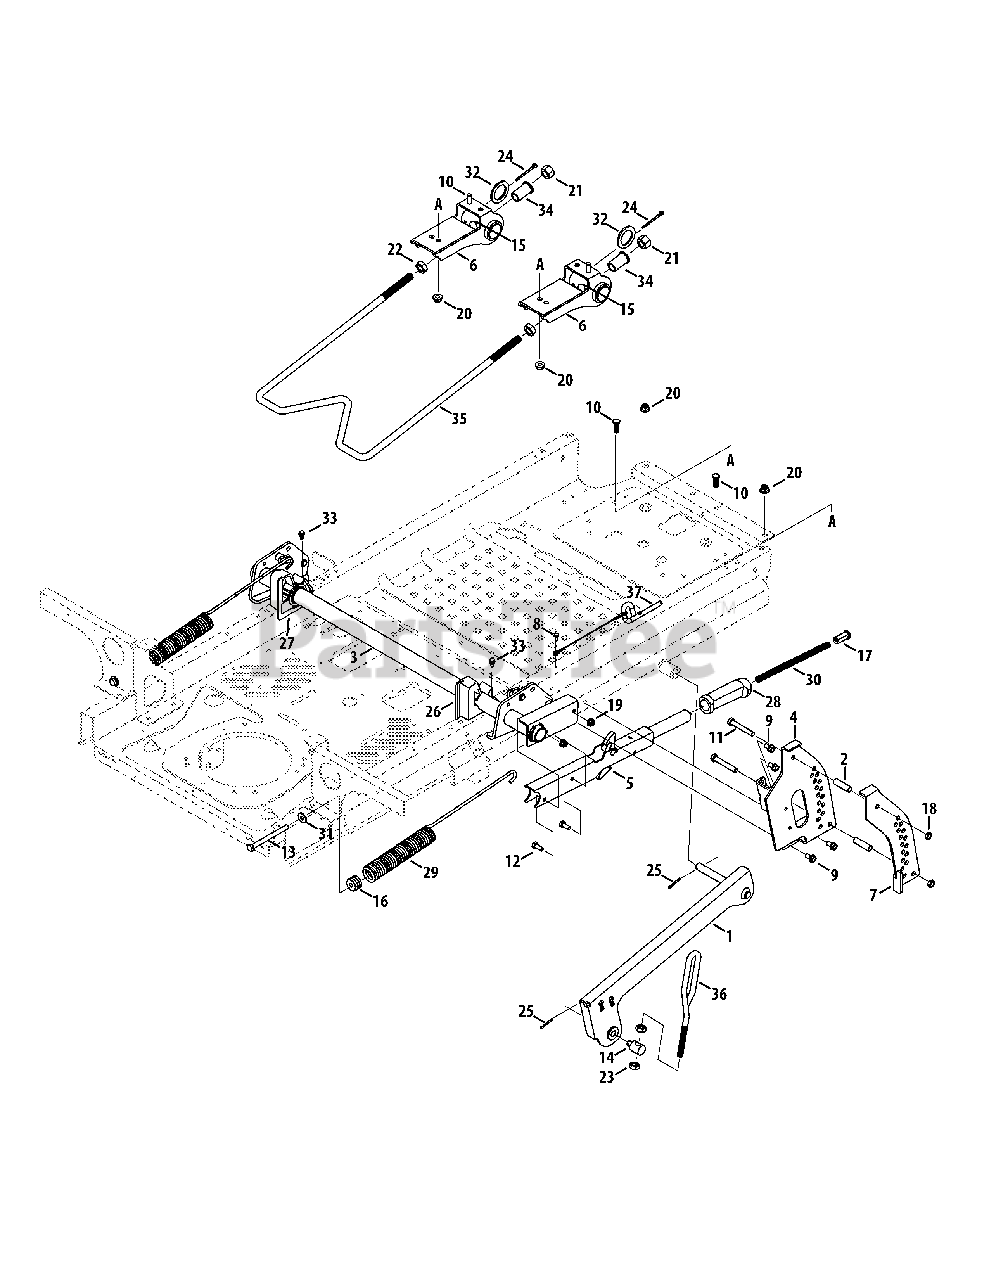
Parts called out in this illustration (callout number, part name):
1	Lift Arm, RH
1	Lift Arm, LH
2	Spacer, .386 x .63 x 1.75
3	Deck Lift Shift Assembly
4	Index Bracket Assembly
5	Latch Handle Assembly
6	Deck Hanger Bracket
7	Outer Index Bracket
8	Screw, #10-16, .50
9	Hex Washer Screw, 5/16-18 x .750
10	Hex Screw, 3/8-16 x 1.00
11	Hex Head Screw, 3/8-16 x 2.50
12	Hex Cap Screw, 5/16-18 x .75
13	Hex Screw, 3/8-16 x 4.25
14	Ferrule, .496 x .528
15	Pivot Pin, 1.25
16	Spring Insert
17	Handle Button
18	Jam Lock Nut, 3/8-16
19	Flange Lock Nut, 5/16-18
20	Flange Lock Nut, 3/8-16
21	Nylock Nut, 5/8-11
22	Jam Nut, 5/8-11
23	Nut,Hex Nylok 1/2-13
24	Cotter Pin, 3/16 x 2.0
25	Cotter Pin 1/8 x 1.25
26	Deck Lift Bracket
27	Deck Lift Bracket, LH
28	Grip, Deck Lift Handle
29	Extension Spring, 1.485 OD x 17.58
30	Spring, Compression, .4 x 8.52
31	Flat Washer, .385 x .870 x .092
32	Flat Washer, 1.875 x 1.38 x .097
33	Shoulder Screw, .500 x 1/4-20
34	Flange Bearing, .875 x .702 x 1.10
35	Deck hanger Rod, 5/8
36	Lift Adjust Link
37	Lock Rod, .375
